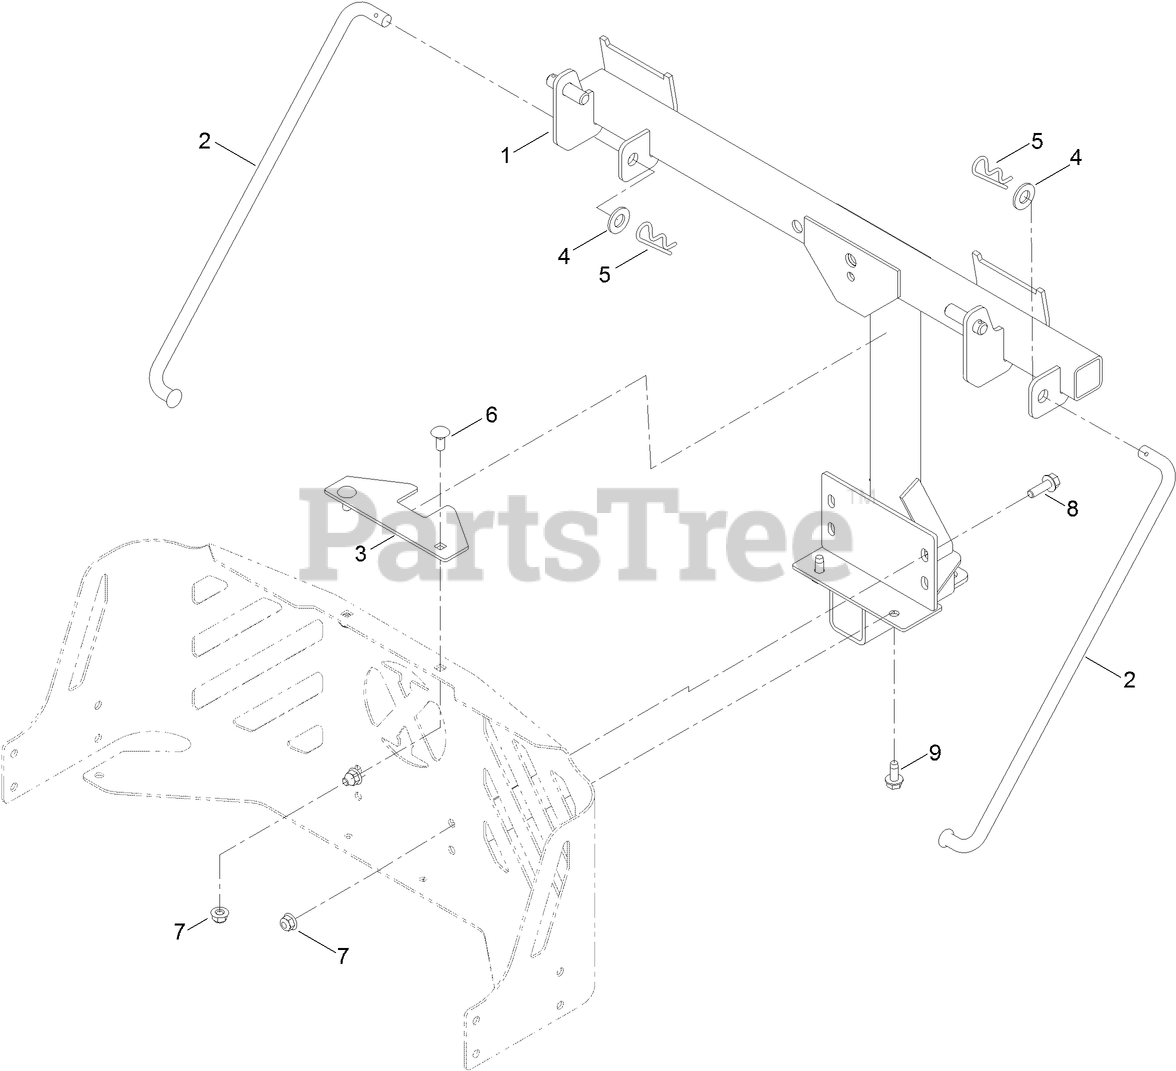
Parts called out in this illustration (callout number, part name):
1	FRAME-PIVOT
2	ROD-SUPPORT
3	BRACKET-STABILIZER
4	WASHER-FLAT
5	PIN-HAIR
6	BOLT-CARR
7	NUT-HF, NI
8	SCREW-HHF
9	SCREW-HWHTF
